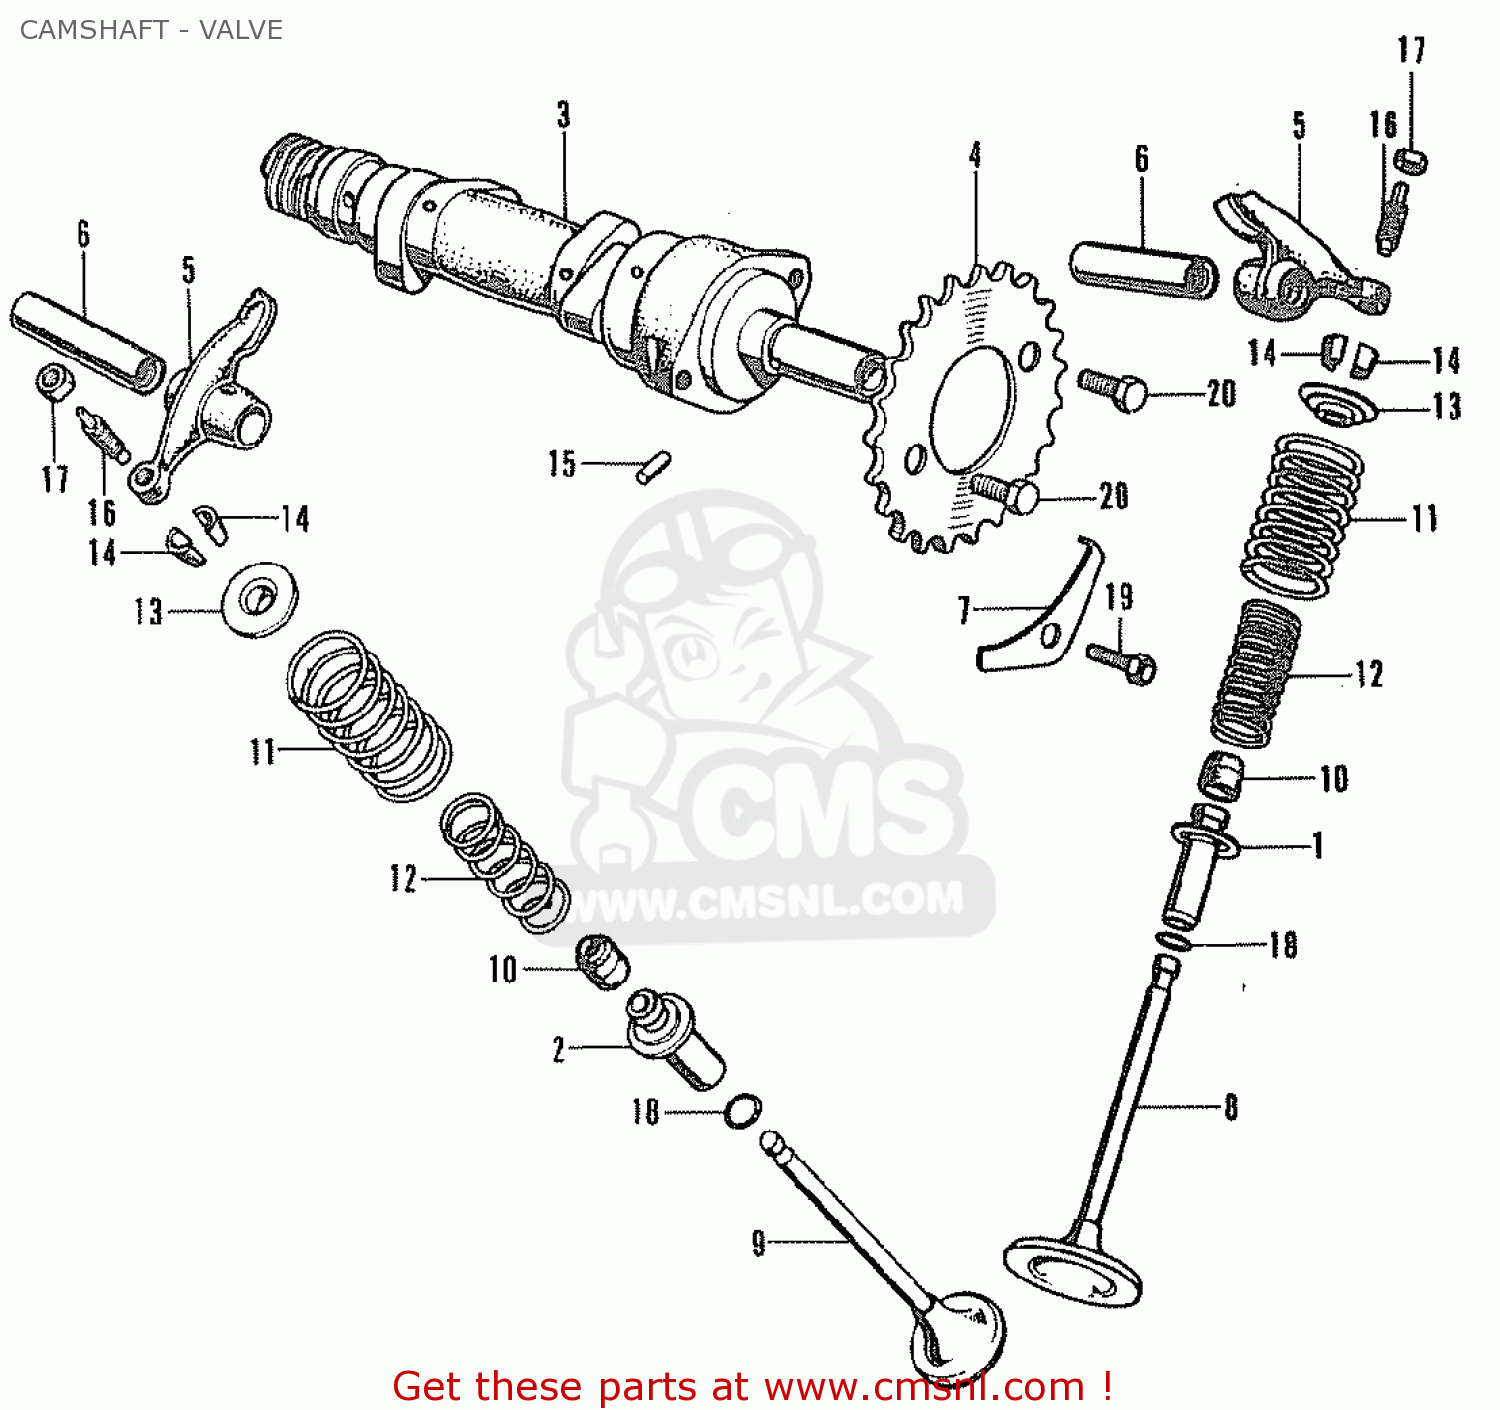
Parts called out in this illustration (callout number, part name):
1	GUIDE,INLET VALVE
2	GUIDE,EXH.VALVE
3	SHAFT CAM
4	SPROCKET,CAM
5	ARM,VALVE ROCKER
6	SHAFT,ROCKER ARM
7	STOPPER,SHAFT
8	VALVE,INLET
9	VALVE EXHAUST
10	SEAL,VALVE STEM
11	SPRING,VALVE
12	SPRING,VALVE
13	RETAINER SPRING
14	COTTER,VALVE
15	PIN, KNOCK, 3X5.2
16	SCREW,TAPPET ADJ.
17	NUT,TAPPET ADJUST
18	O RING 9.0X1.6
19	BOLT,HEX 5X12
20	BOLT,HEX 6X10
